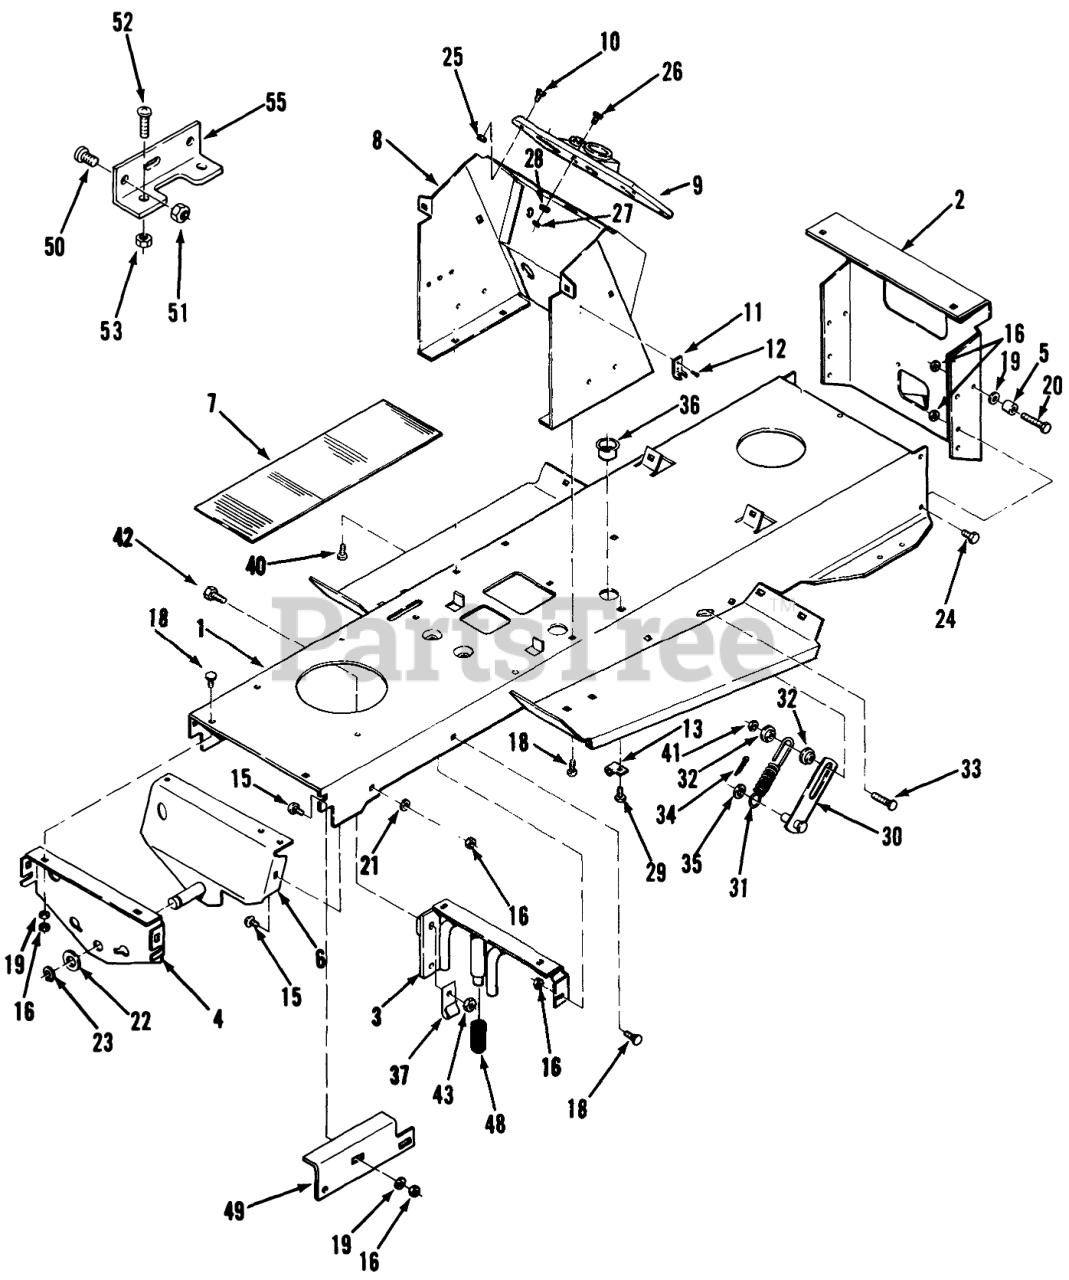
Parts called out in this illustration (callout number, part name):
1	Frame
2	PLATE-DRAWBAR R
3	Frame Support Plate
4	PLATE SUPT - AXLE R
5	BEARING-CAM ROLLER
6	Axle Support-Rear
7	Footrest Mat-Deluxe LH
8	Hoodstand
9	CONSOLE
10	SCREW #10X.62 PHCR
11	Latch Keeper
12	RIVET
13	J-CLIP
15	Bolt-Carriage
16	Nut
18	Bolt
19	WASHER 5/16 SAE
20	Bolt
21	Washer-Lock
22	WASHER
23	Snap Ring
24	Bolt
25	Nut
26	Screw
27	Nut
28	Washer
29	Bolt
30	ASSY LINK B
31	SPRING
32	BUSHING
33	Bolt-Carriage
35	WASHER
36	BUSHING-NYLON 1.093
37	CLIP
40	Bolt
41	Nut
42	Bolt
43	NUT
49	BRACKET R.H. R
50	Screw
51	Nut
52	Screw
53	Nut
55	BRKT-FUSE HOLDER B
